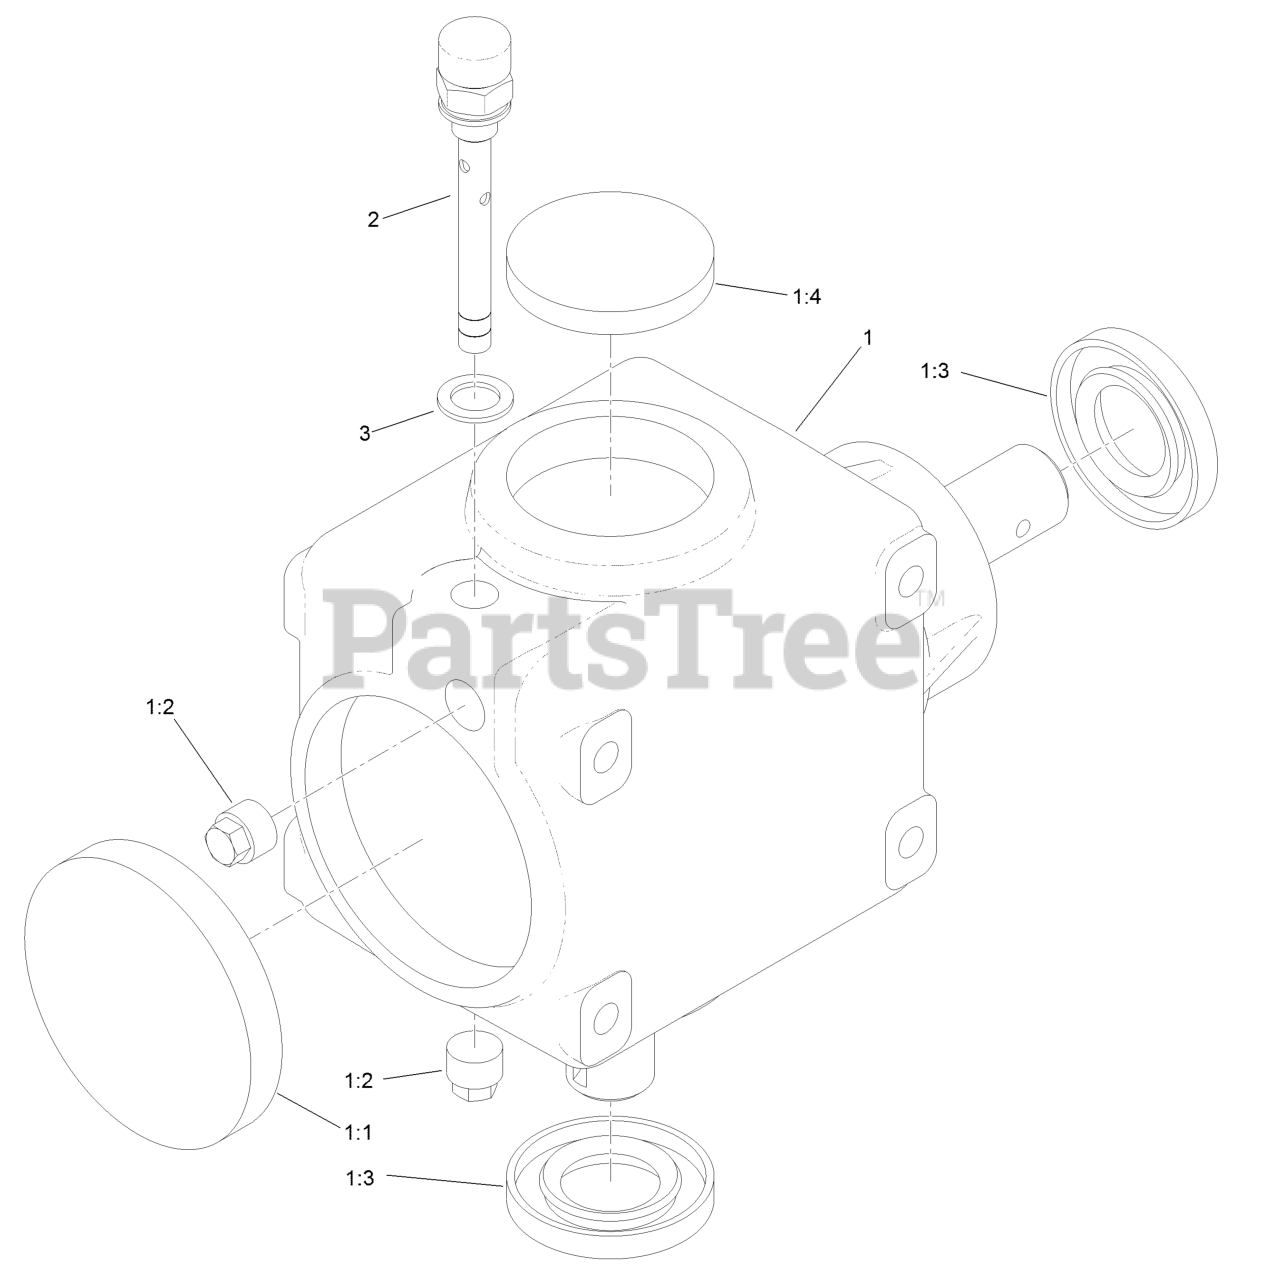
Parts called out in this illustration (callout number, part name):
1	Gearbox ASM
1:1	Cap-Oil
1:4	Cap-Oil
2	Plug-Breather
